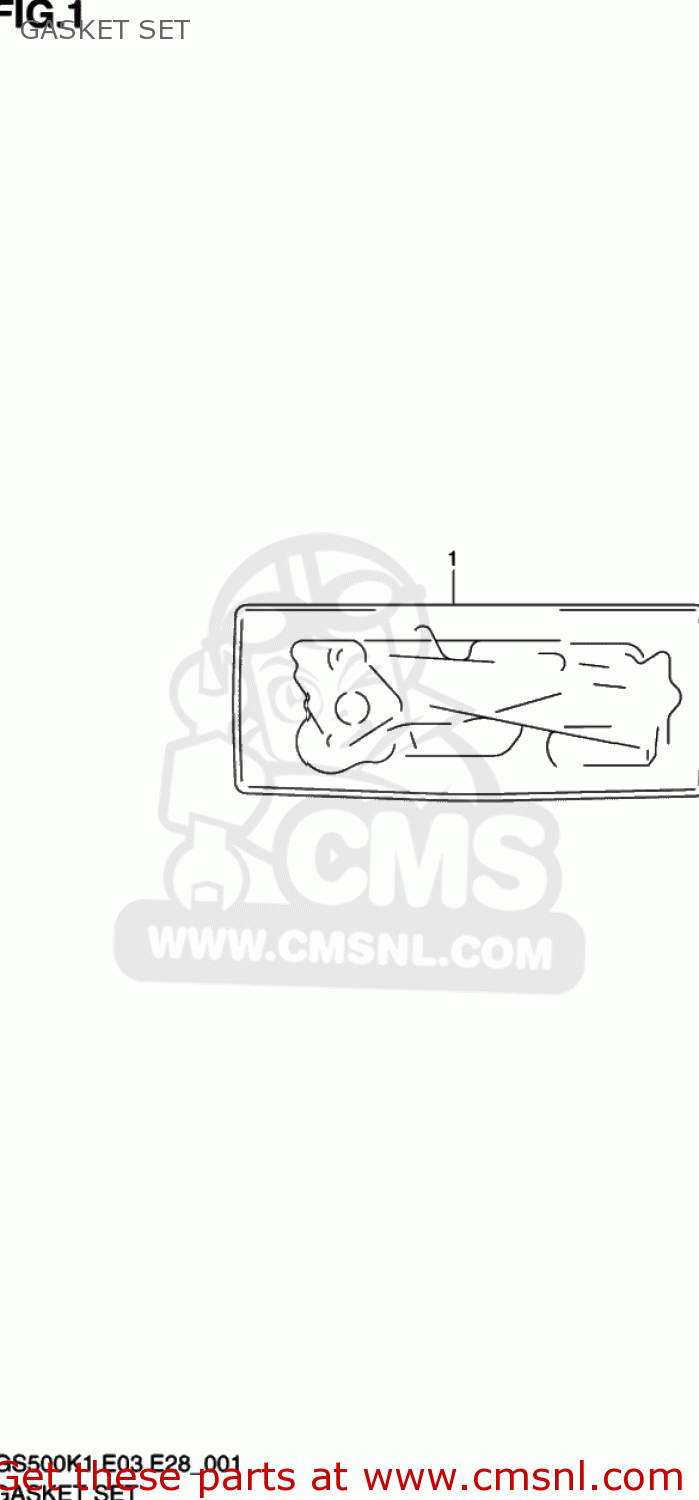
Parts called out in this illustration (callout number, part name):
1	GASKET SET
2	GASKET,CYLINDER HEAD (NAS)
3	O RING,HEAD GASKET
4	GASKET,CYLINDER HEAD COVER (NAS)
5	GASKET,BREATHER COVER (NAS)
6	GASKET,CYLINDER (NAS)
7	GASKET,CLUTCH COVER (NAS)
8	GASKET,MAGNETO COVER (NAS)
9	GASKET,OIL PAN(ASB) (NAS)
10	GASKET,TENSIONER ADJUSTER (NAS)
11	GASKET,EXHAUST PIPE (NAS)
12	O RING,OIL FILTER CHAMBER CAP
13	GASKET(5.8X13X1.2) (NAS)
14	GASKET 8.2X14X1 (NAS)
15	GASKET(10.2X20X2).3 (NAS)
16	GASKET(14X19.2X2) (NAS)
17	O RING(D:1.05,ID:3.1)
18	O RING(D:1.9,ID:13)
19	O RING(D:1.9,ID:14.5)
20	O RING(D:3.1,ID:26.4)
21	O RING(D:2.4,ID:39.7)
